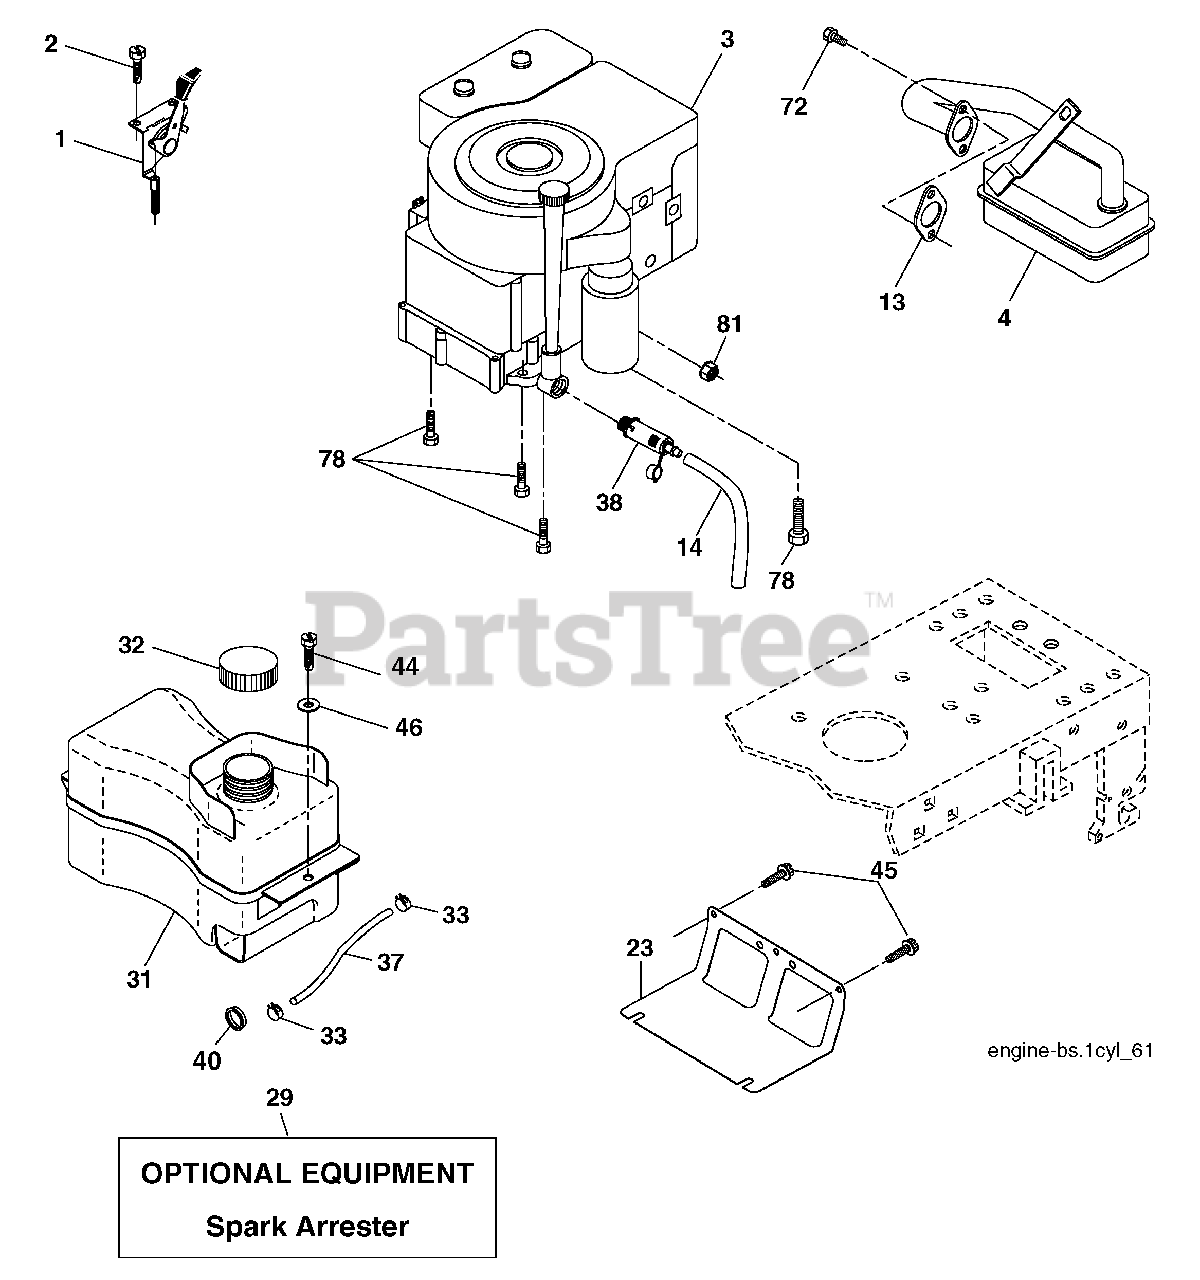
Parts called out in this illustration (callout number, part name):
1	Control Th/ch Flag
2	Screw Hex Thd Cut 1/4-20 x 1/2
4	Muffler Exhaust B&S
13	Gasket Eng 1 313 Id Tin Plated
14	Tube Drain Oil Easy
23	Shield BRN/DBR Guard
29	Kit Spark Arrestor (Flat Scrn)
31	Tank Fuel Front
32	Cap Asm Fuel
33	Clamp Hose
37	Line Fuel
38	Plug Drain Oil
40	Bushing Snap Nyl Blk Fuel Line
44	Screw Thdrol 1/4-20 x 3/4
45	Screw Hex Wsh Thdrol 3/8-16
46	Washer 9/32 x 7/8 x 16 Ga.
72	Screw Socket Head 5/16-18 x 3/4
78	Screw 3/8-16 x 1-1/4
81	Nut Keps Hex 1/4-20 unc
